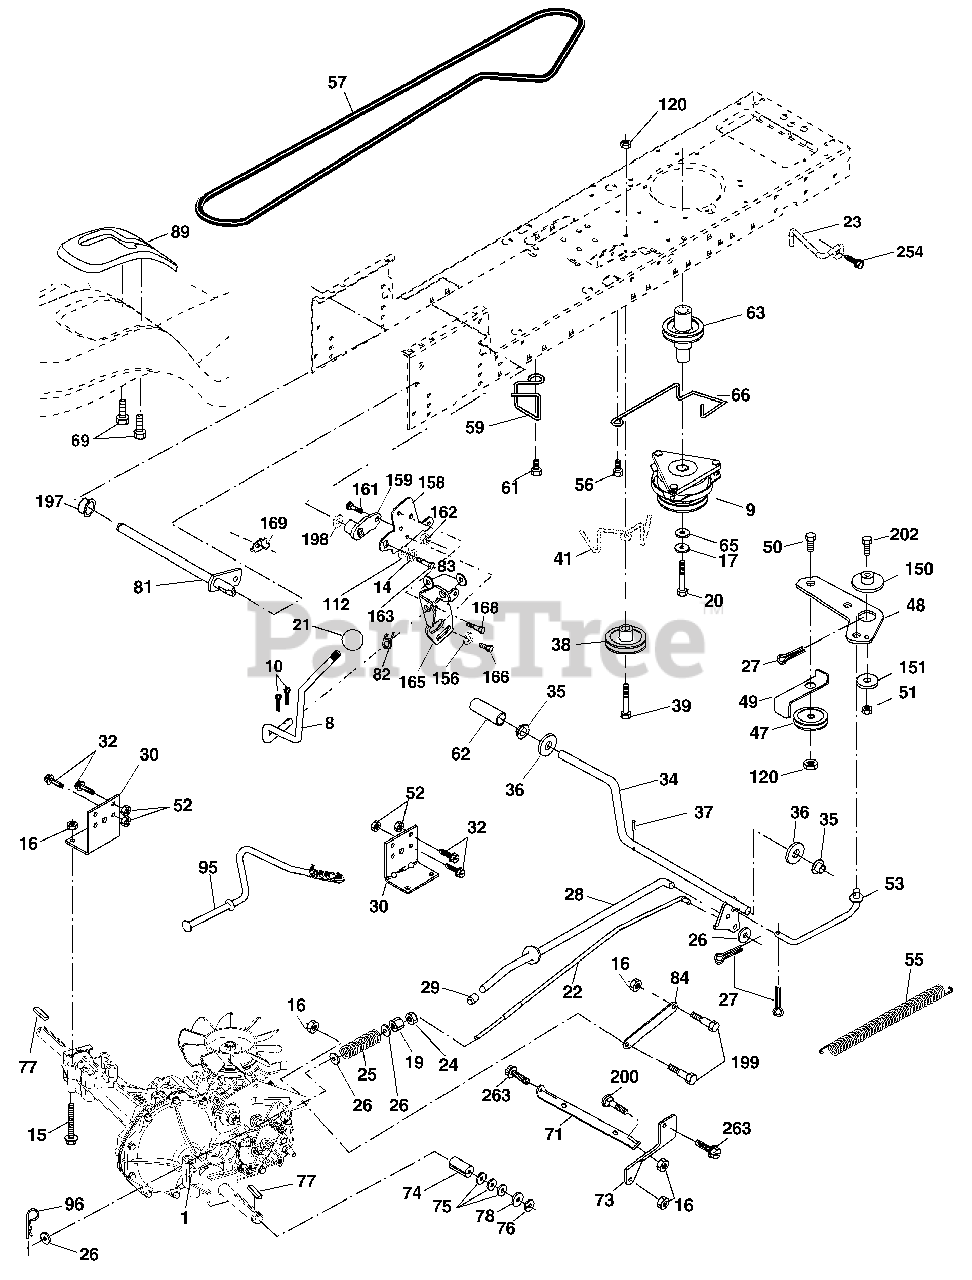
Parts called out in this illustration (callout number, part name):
8	Rod Shift Fend.
9	Clutch Electric
10	Pin Cotter 1/8 x 1
14	Washer Lock Hvy 1/4
15	Bolt Hex Flghd 5/16-18 Gr. 5
16	Nut Lock Hex W/Ins. 5/16-18 unc
17	Washer 1-1/2 OD x 15/32 ID x.250
19	Nut Lock Hex W/Wsh 3/8-16 unc
20	Bolt Hex 7/16-20 x 4 x Gr. 5-1.5
21	Knob
22	Rod, Brake
23	Bracket Anti-Rotation
24	Nut, Hex Jam 3/8-16 unc
25	Spring, Brake Rod
26	Washer
27	Pin Cotter 1/8 x 3/4 CAD.
28	Rod, Parking Brake
29	Knob Brake Parking
30	Bracket, Transaxle
32	Bolt Hex Hd 5/16-18 unc x 3/4
34	Shaft, Foot Pedal
35	Bearing, Nylon
36	Washer
37	Pin, Roll
38	Pulley, Composite
39	Bolt Rdhd 3/8-16 unc x 2-3/4 Gr. 5
41	Keeper, Belt Idler Flat
47	Pulley, Idler, V-Groove
48	Bellcrank Clutch Grnd Drw Stl
49	Retainer, Belt
50	Bolt
51	Nut Crownlock 3/8-16 unc
52	Nut, Crownlock 5/16-18 unc
53	Link, Clutch
55	Spring, Return, Clutch
56	Screw 3/8-16 x 1-1/4
57	V-Belt, Ground Drive
59	Keeper, Center Span
61	Screw 3/8-16 x .875
62	Cover, Pedal
63	Pulley, Engine
65	Washer
66	Keeper Belt Engine
69	Screw Hex Wsh Hi-Lo 1/4-1/2 unc
71	Strap Torque LH
73	Strap Torque RH
74	Spacer, Axle
75	Washer 25/32 x 1-1/4 x 16 Ga.
76	E-Ring
77	Key, Square
78	Washer 25/32 x 1-5/8 x 16 Ga.
81	Shaft Assy. Cross Taper
82	Spring Torsion
83	Washer 17/32 x 3/4 x 16 Ga.
84	Link Transaxle
89	Console, Shift
95	Rod Bypass
96	Retainer Spring 1" Zinc/Cad
116	Bolt RDHD SQNK 3/8-16 unc x 1
120	Nut Lock Flg 3/8-16 unc
150	Spacer Retainer
151	Washer 13/32 x 2 x 10 Ga.
156	Washer 5/16 ID x 1.0 x .125
158	Bracket Shift Mount
159	Hub Shift
161	Bolt Rdhd Sqnk 1/4-20 x 3/4 Gr. 5
162	Nut Crownlock 1/4-20 unc
163	Bolt Hex Fin 1/4-20 unc x 1 Gr. 5
164	Washer 9/32 x 3/4 x 10 Ga.
165	Bracket Pivot Lever
166	Screw 5/16-18 x 5/8
168	Bolt Shoulder 5/16-18 x .561
169	Plate Fastener Cross Shf.
197	Nyliner Snap-in 5/8 ID
198	Washer Nyl 7/8 ID x .105"
199	Bolt Shoulder 5/16-18 unc
200	Bolt Rdhd Sqnk 5/16-18 unc x 1
202	Bolt Carr Sh 3/8-16 x 1-3/4 Gr. 5
212	Nut Hex Flange Lock
254	Screw 3/8-16 x 1
271	Screw 3/8-16 x .75
